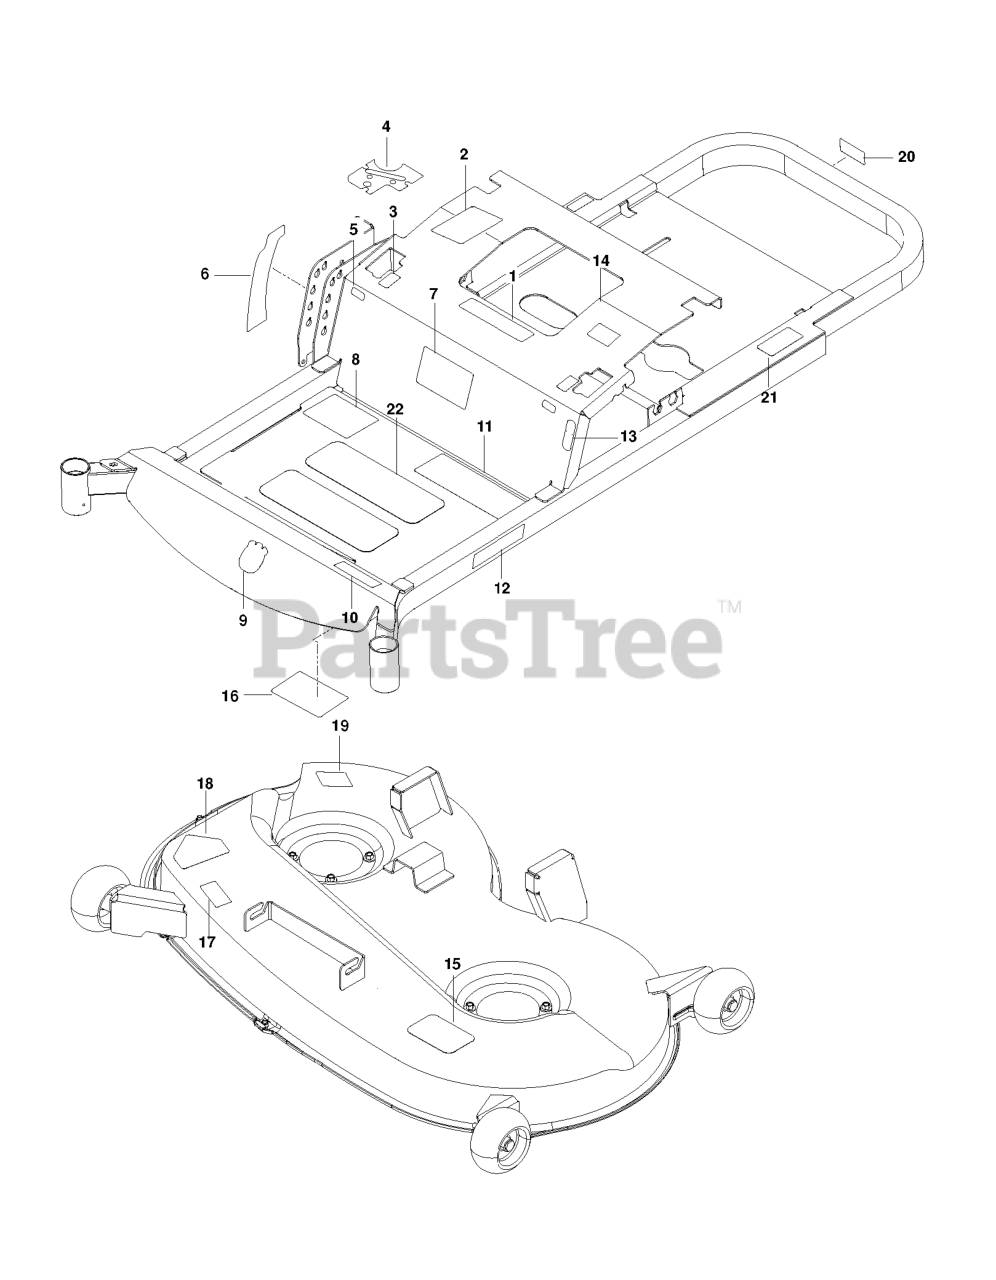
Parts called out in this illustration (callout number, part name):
1	EURO DECAL-BATTERY WARNIN6
2	DECAL, CUSTOMER RESPNSIBILITY
3	DECAL, MOTION CONTROL
4	DECAL, CTRL PANEL HUS WO CHOKE
5	DECAL, F.S.T.
6	DECAL, HEIGHT
7	DECAL, START
8	DECAL, WARNING
9	DECAL.AUGER.HUSQ.CROWN.SNOW
10	DECAL, RZ4621 (BF UNIT)
11	DECAL, SAFETY WARNING
12	RP.DECAL.BADGE.170MM.TEXTLOGO
13	DECAL, PARK BRAKE
14	DECAL, EXITING MOWER
15	DECAL, BELT ROUTING
16	DECAL, SERVICE
17	DECAL, EURO SEVERING
18	DECAL, CPSC
19	DECAL, CAUTION
20	DECAL, PROP. 65
21	DECAL, DO NOT TOW
22	ANTI-SKID PAD
